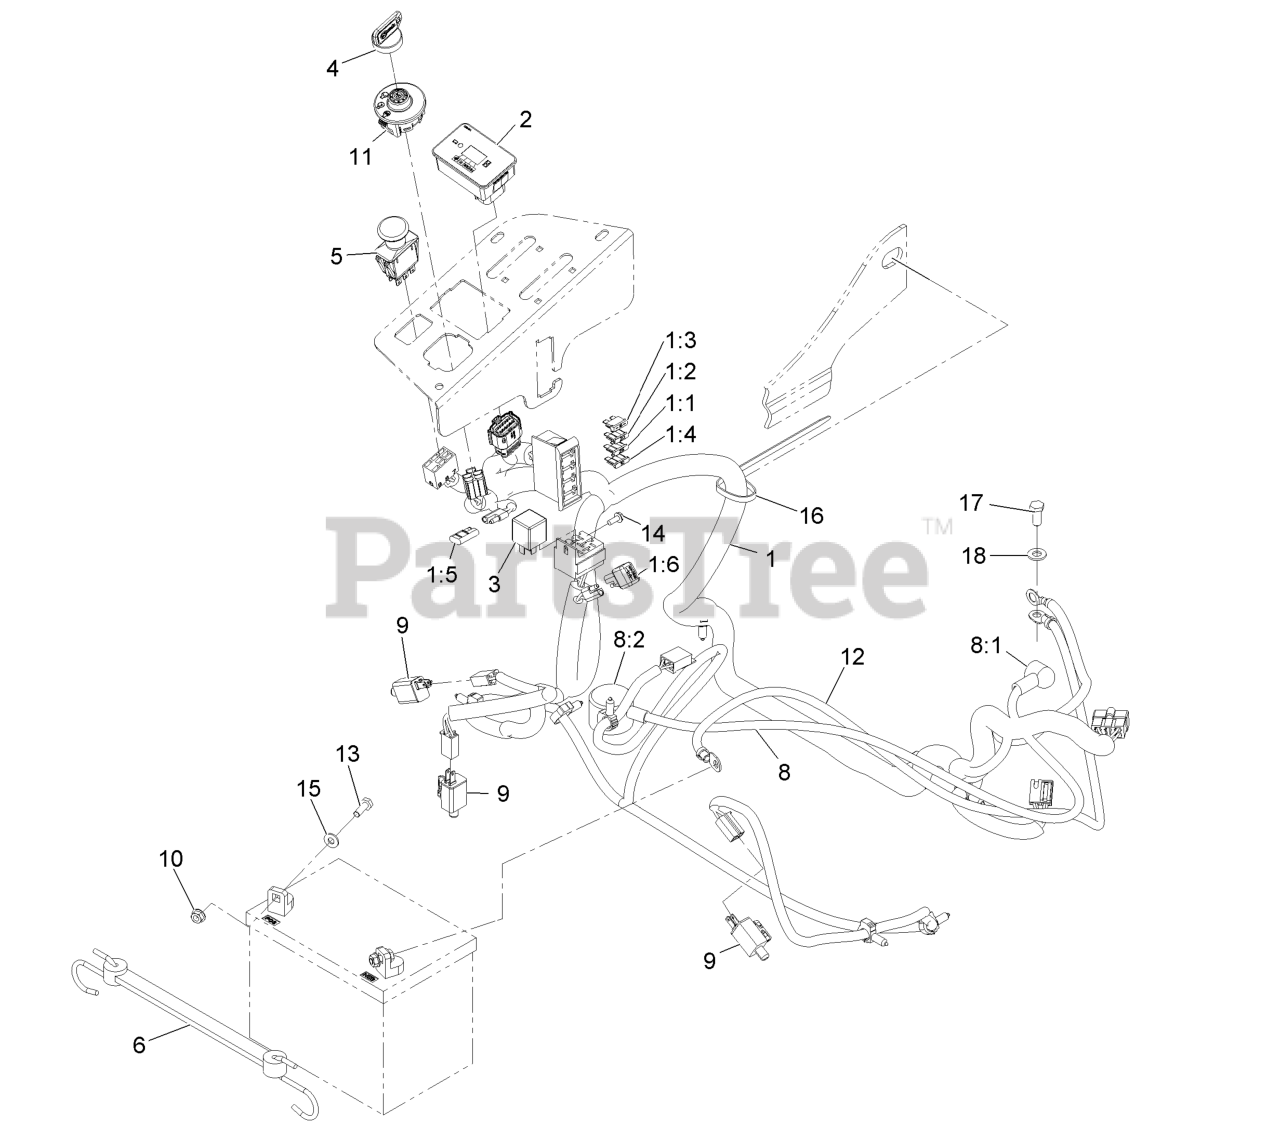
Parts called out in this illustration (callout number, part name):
1	HARNESS, WIRE
1:1	FUSE-BLADE, 25 AMP
1:2	FUSE-BLADE TYPE, 20 AMP
1:3	FUSE-BLADE, 15 AMP
1:4	FUSE-BLADE, 10 AMP
1:5	CAP-PLUG
4	KEY-IGNITION
5	SWITCH-PTO
6	HOLDDOWN-BATTERY
8	POSITIVE BATTERY CABLE AS
8:1	INSULATOR-SOLENOID
8:2	INSULATOR-BATTERY
12	CABLE-BATTERY, NEGATIVE
13	SCREW-HH
14	SCREW-TAPTITE
15	WASHER-FLAT
16	TIE-PLASTIC
17	SCREW-HH
18	WASHER-PLAIN
